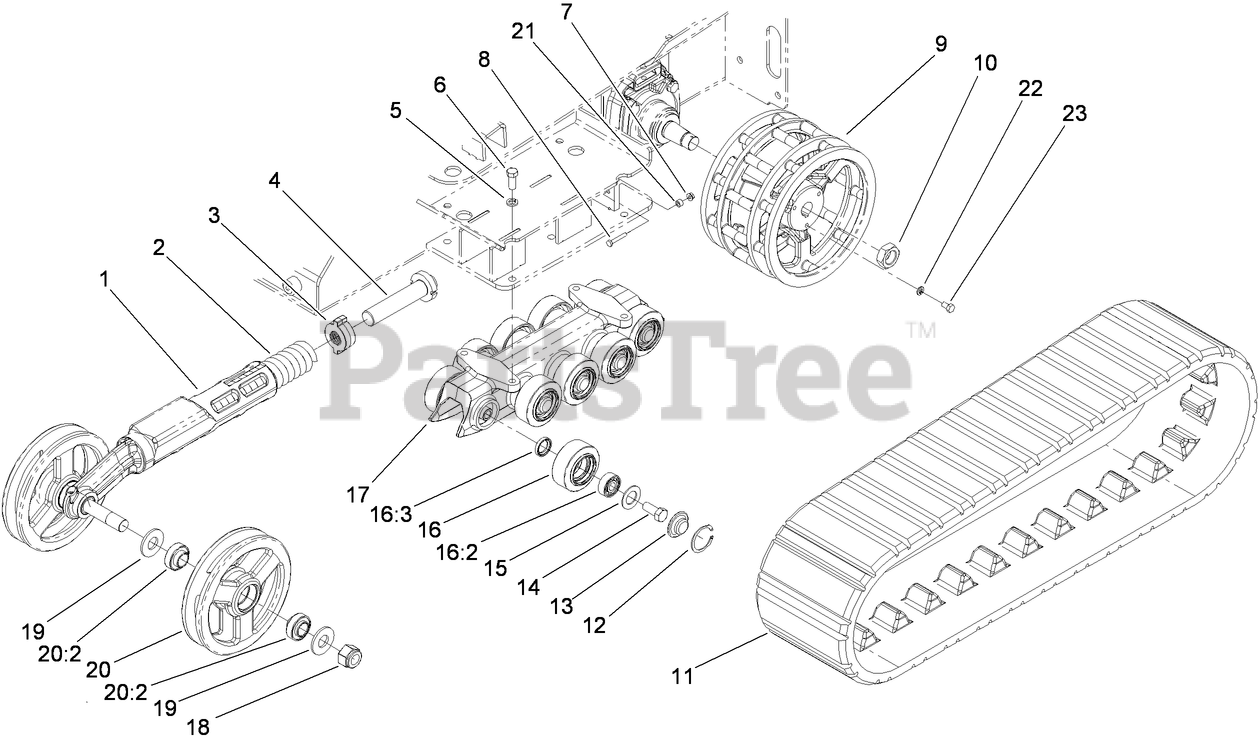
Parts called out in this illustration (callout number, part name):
1	ARM-TENSIONER
2	SPRING-COMPRESSION
3	BLOCK-TENSIONER
4	BOLT-TENSIONER
5	WASHER-LOCK
6	SCREW-HH
7	NUT-HHF
8	SCREW-HH
9	WHEEL-DRIVE
10	NUT-HEX
11	TRACK
12	RING-SNAP, INTERNAL
13	CAP-WHEEL, BEARING
14	SCREW-HH
15	Gasket-Bogie
16	Road Wheel ASM
16:2	BEARING-BALL
16:3	SEAL-OIL
17	GUIDE-TRACK
18	NUT-HEX, NI
19	WASHER-PLAIN
20	Tensioner Wheel ASM
20:2	Bearing-Ball
21	SPACER
22	WASHER-LOCK
23	SCREW-HH
